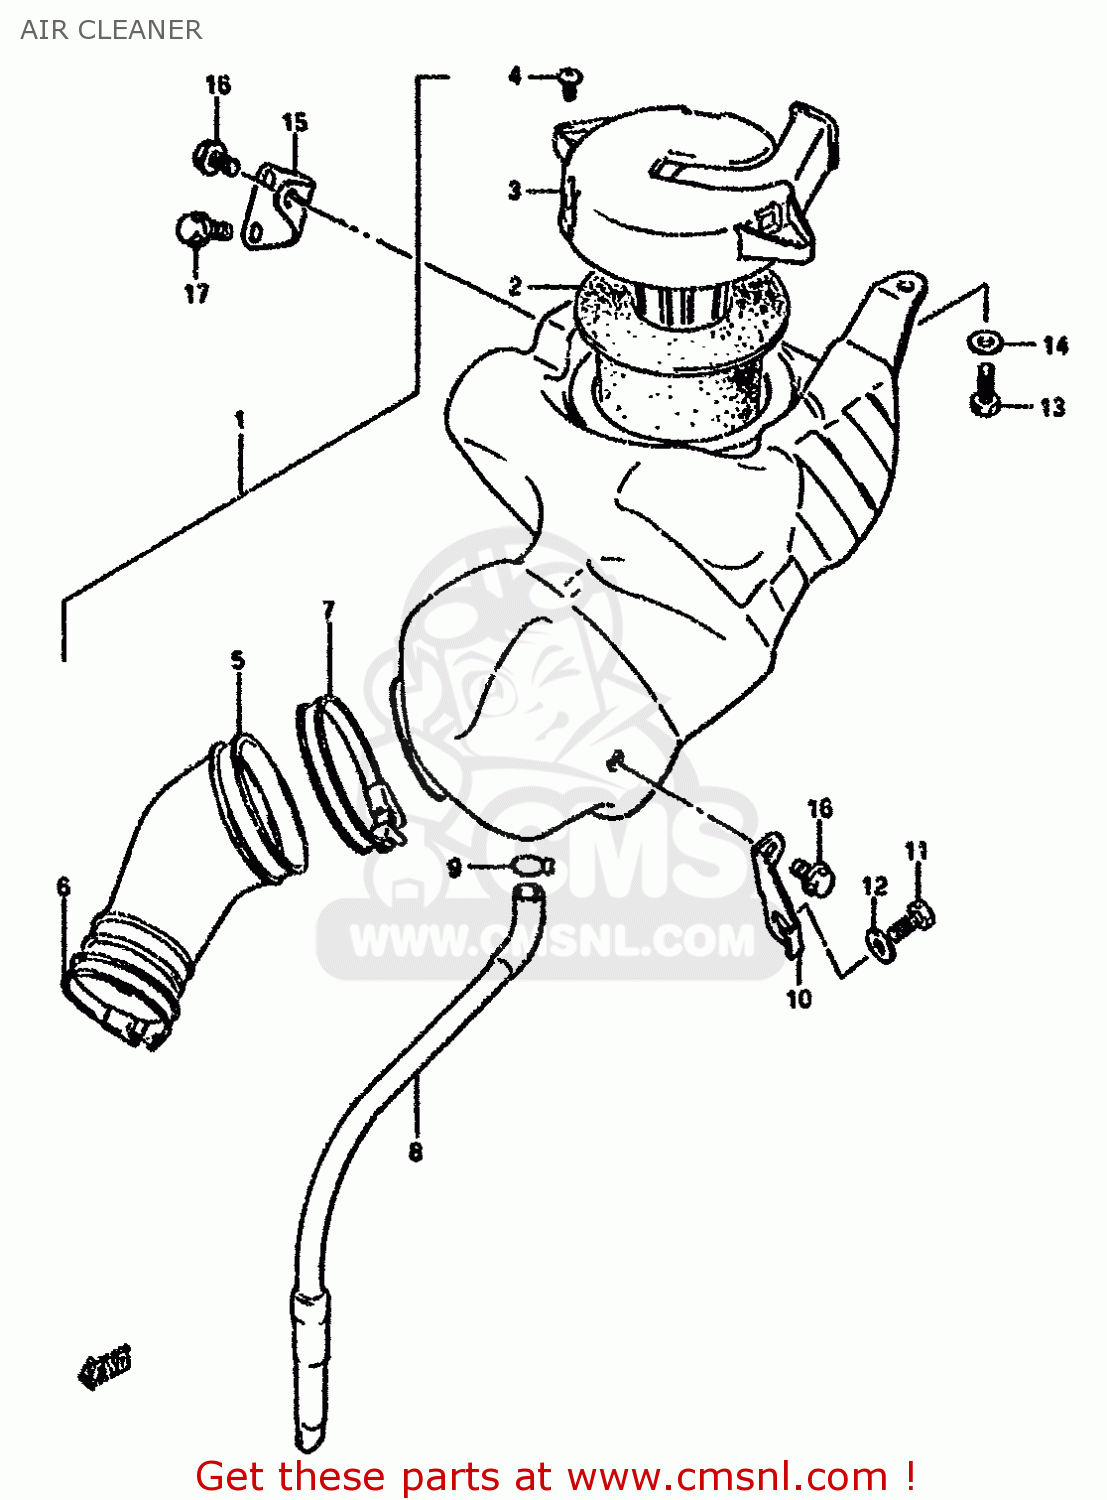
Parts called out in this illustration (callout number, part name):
1	CLEANER ASSY,AIR
2	FILTER
3	TUBE,AIR CLEANER OUTLET
4	SCREW
5	TUBE,AIR CLEANER OUTLET
6	CLAMP
7	CLAMP
8	TUBE,DRAIN
9	CLIP
10	BRACKET, AIR CLEANER
11	BOLT
12	WASHER
13	BOLT
14	WASHER(6.5X16X1.2)
15	BRACKET,AIRCLEANER
16	BOLT
17	BOLT
